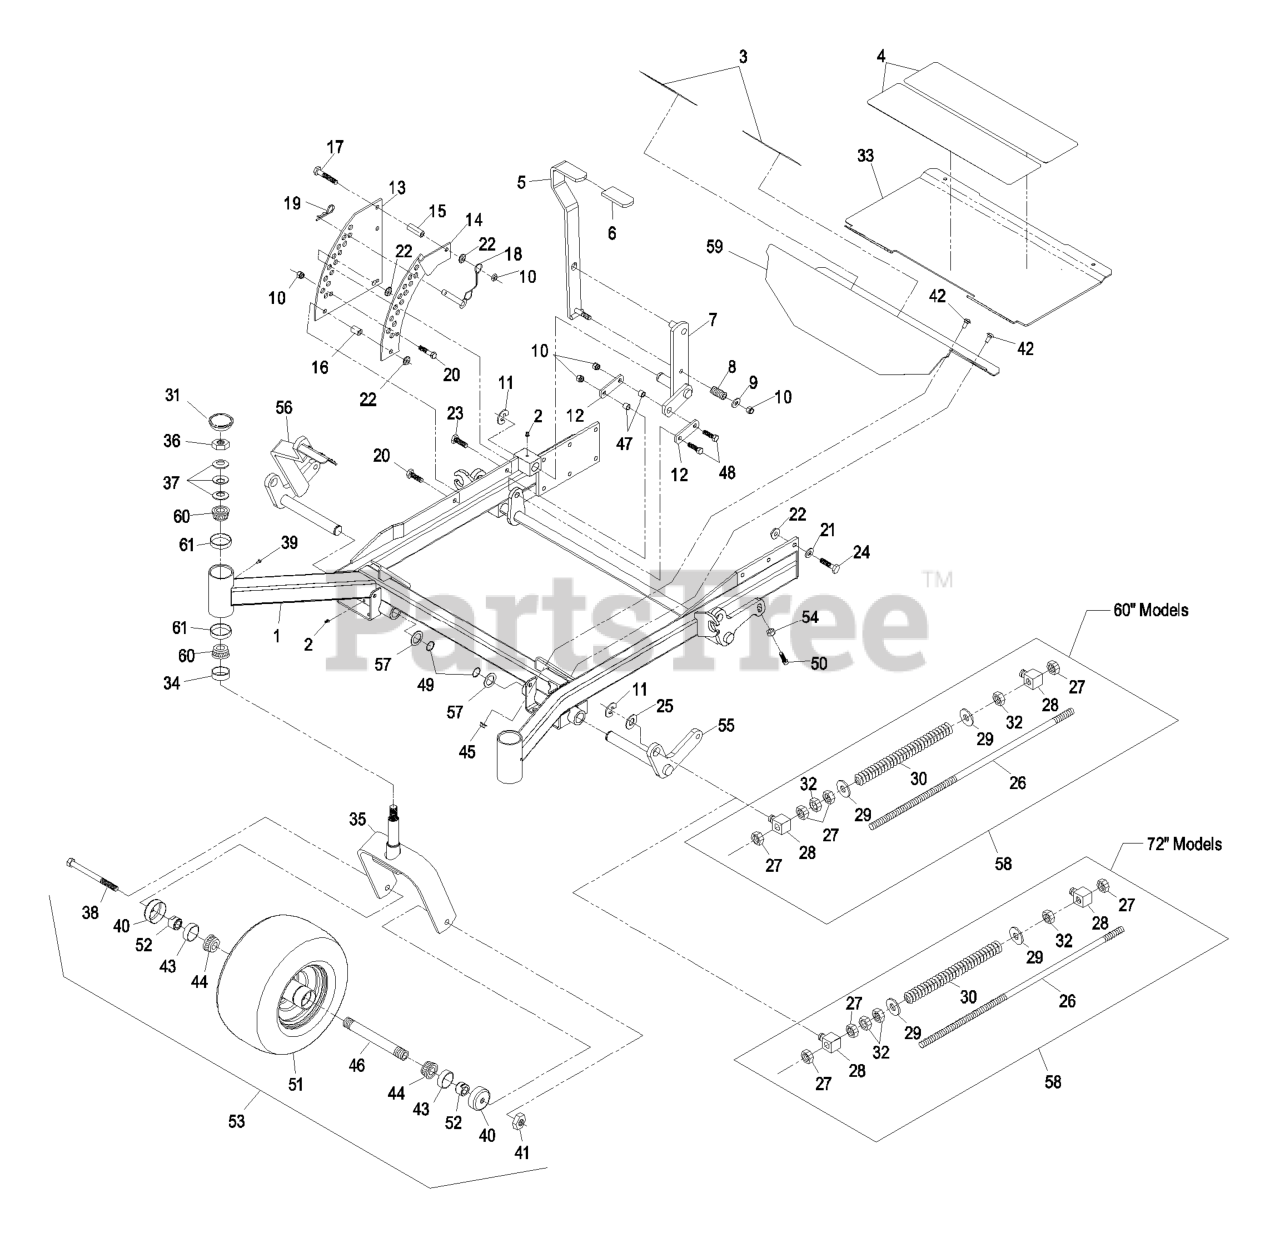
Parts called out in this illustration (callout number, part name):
1	KIT,FRONT FRAME LZ 60
2	FITTING-GREASE
3	PAD-ANTI SKID
4	PAD-ANTISKID
5	LIFT LEVER/GRIP ASM
6	GRIP-LEVER, LIFT
7	ARM-LIFT, DECK
8	SPRING-COMPRESSION
9	WASHER-FLAT
10	NUT-LOCK, NI
11	RING-RETAINING, EXT
12	ARM-LIFT, DECK
13	PLATE-LIFT, DECK
14	PLATE-LIFT, DECK
15	BUSHING-LEVER, LIFT
16	BUSHING-LEVER, LIFT
17	SCREW-HH
18	PIN-HITCH (W/LANYARD)
19	PIN-COTTER
20	SCREW-HH
21	WASHER-BELLEVILLE
22	NUT-HHF, WHIZ
23	SCREW-HH
24	SCREW-HH
25	WASHER-FLAT
26	ROD-LIFT, DECK
27	NUT-HEX
28	SWIVEL-DECK MOUNT, REAR
29	WASHER-FLAT
30	SPRING-SUPPORT, DECK
31	CAP-GREASE
32	NUT-JAM
33	ASM,LIFTOUT FLOORPAN/PAD
34	SEAL-GREASE
36	NUT-LOCK, NI
37	WASHER-BELLVILLE
38	SCREW-HH
40	GUARD-SEAL
41	NUT-LOCK, NI
42	BOLT-CARR
43	SEAL-CASTER
44	BEARING-CONE, TAPERED ROLLER
47	BUSHING
48	SCREW-HH
49	RING-RETAINING
50	SCREW-HSH
52	SPACER-NUT
54	NUT-JAM
55	WLD, FRONT LIFT SHAFT - L
56	WLD, FRONT LIFT W/ LEVER
57	WASHER-SPACER
58	FRONT FRAME SPRING ASM
60	Cone-Bearing Tapered Roller
61	CUP-BEARING
